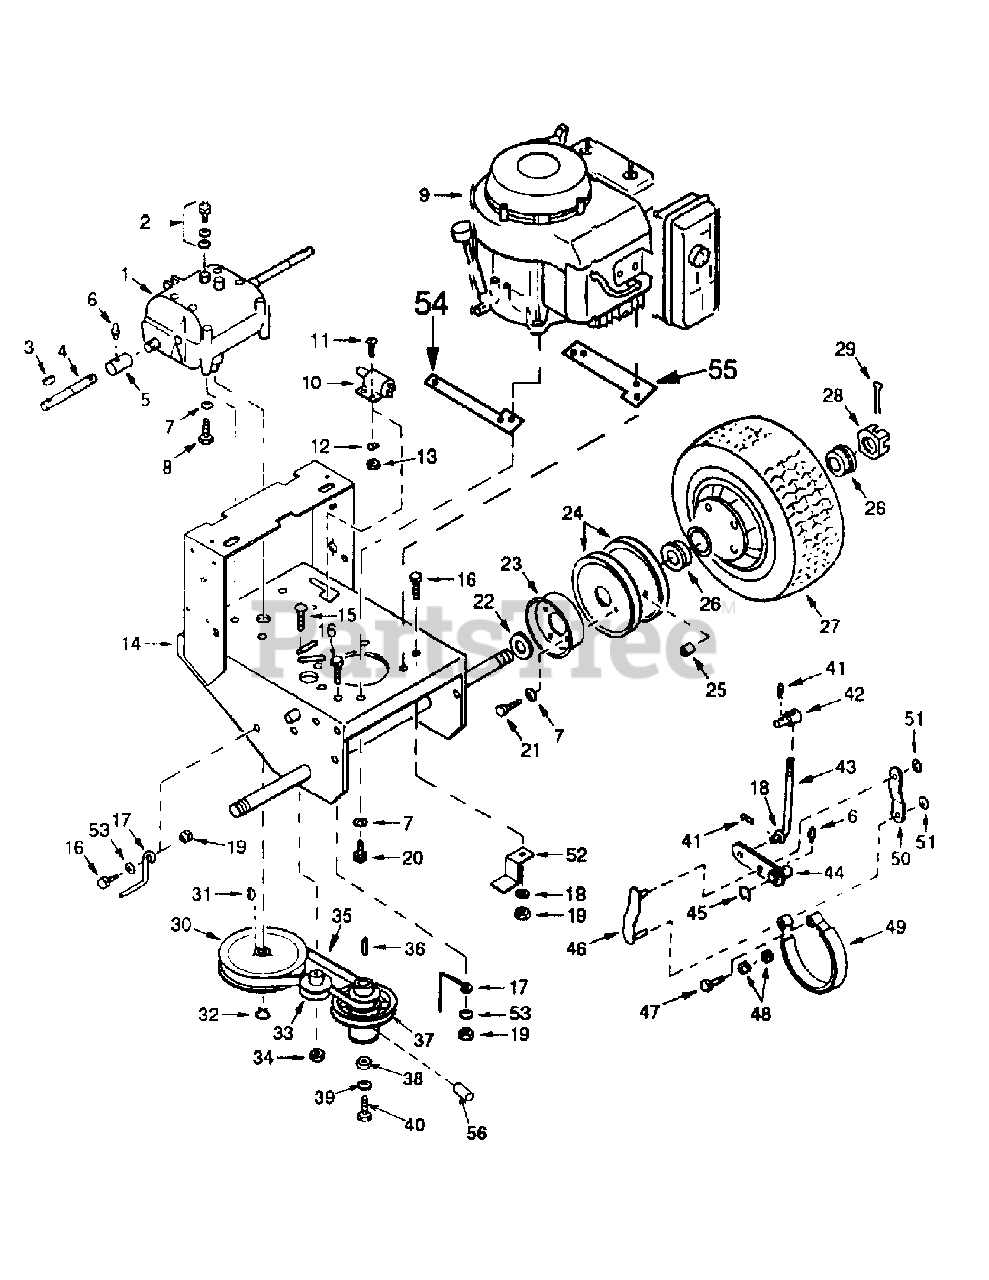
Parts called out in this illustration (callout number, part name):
1	Transmission
2	Neutral Safety Switch
3	Woodruff Key
4	Jackshaft
5	Coupler
6	Grease Fitting, 1/4-28 Straight
7	Lock Washer, 5/16
7	Lock Washer, 3/8 Internal
8	Cap Screw, 5/16-18 x 3/4 Hex Hd.
9	Engine, Kawasaki, 14.0 HP
9	Engine, Kawasaki, 17.0 HP, Electric Start
9	Engine, Kohler, 14.0 HP
9	Briggs & Stratton
10	Blade Safety Switch
10	Blade Safety Switch, Electric Start Engine
11	Machine Screw, #10-32 x 1/2 Rd. Hd.
12	Hex nut, 10-32 Nylock
13	(Purchase Locally)
14	Engine Deck, 32" Mower
14	Engine Deck, 36" & 48" Mowers
15	Carriage Bolt, 3/8-16 x 2
16	Carriage Bolt, 5/16-18 x 1 Hex Hd.
17	Belt Guide
18	Flat Washer, 5/16
19	Hex Nut, 5/16-18 Nylock
20	Cap Screw, M8-1.25TH x 25MM Hex Hd.
21	Cap Screw, 5/16-18 x 1-1/2 Hex Hd.
22	Flat Washer, 1"
23	Brake Drum
24	Drive Pulley
25	Spacer
26	Wheel Bearing
27	Tire and Wheel Ass'y., 32" Mower
27	Tire and Wheel Ass'y., 36", 48" & 52" Mowers
28	Axel Nut, 1-14 Slotted Hex Hd.
29	Cotter Pin, 5/32 x 1-1/2
30	Drive Pulley
31	(Purchase Locally)
32	Retaining Ring, External
33	Idler, Take-Up
34	Hex Nut, 3/8-16 Nylock
35	Drive Belt
36	Key, 1/4 x 1/4 x 2-1/2
37	Pulley, Traction Drive
38	Clutch Plated Washer
39	7/16 Lock Washer
39	M10 Lock Washer
40	7/16 Bolt
40	M10 x 50mm
41	Hairpin, 3/8-7/16
42	Swivel Joint
43	Brake Rod
44	Brake Lever
45	E-Ring, 5/8
46	Brake Link w/Pins
47	Cap Screw, 3/8-16 x 2 Hex Hd.
48	Hex Nut, 3/8-16
49	Brake Band
50	Brake Link
51	Retainer, 3/8 Push-On
52	Belt Guide
53	Flat Washer, 3/8, Thick
54	Engine Spacer, Right Hand
55	Engine Spacer, Left Hand
56	Engine Pulley Spacer
57	Grease Fitting, 90° 1/4-28
58	Washer, Flat 3/8
59	Support Clamp 1/2
